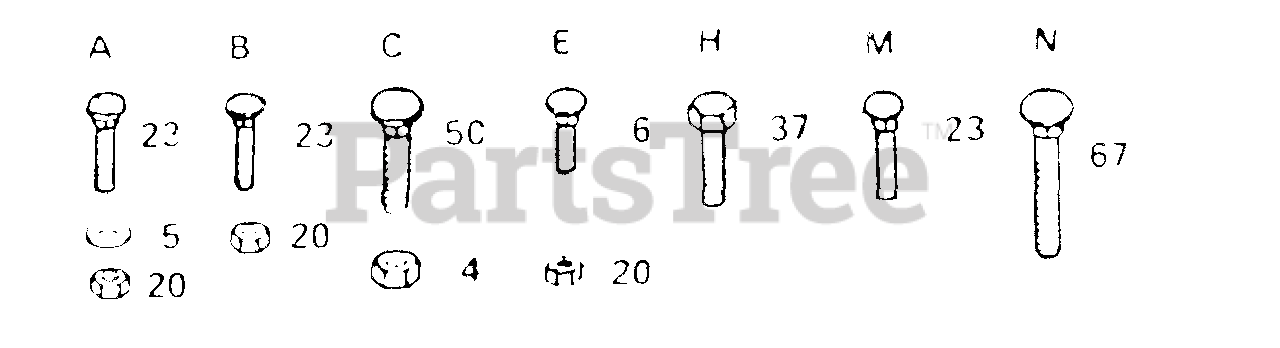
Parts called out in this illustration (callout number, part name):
4	Nut, Lock, 3/8-16
5	Washer, 11/32 x 3/4 x 16 Ga.
6	Bolt, Carr., 5/16-18 x 5/8
20	Nut, Lock 5/16-18
23	Bolt, Carriage 5/16-18 x 3/4
37	Screw - Hex Washer Hd. 3/8-16 x 1 1/4
50	Bolt, Carriage 3/8-16 x 3/4
67	Bolt, Carr. 3/8-16 x 1-1/4
